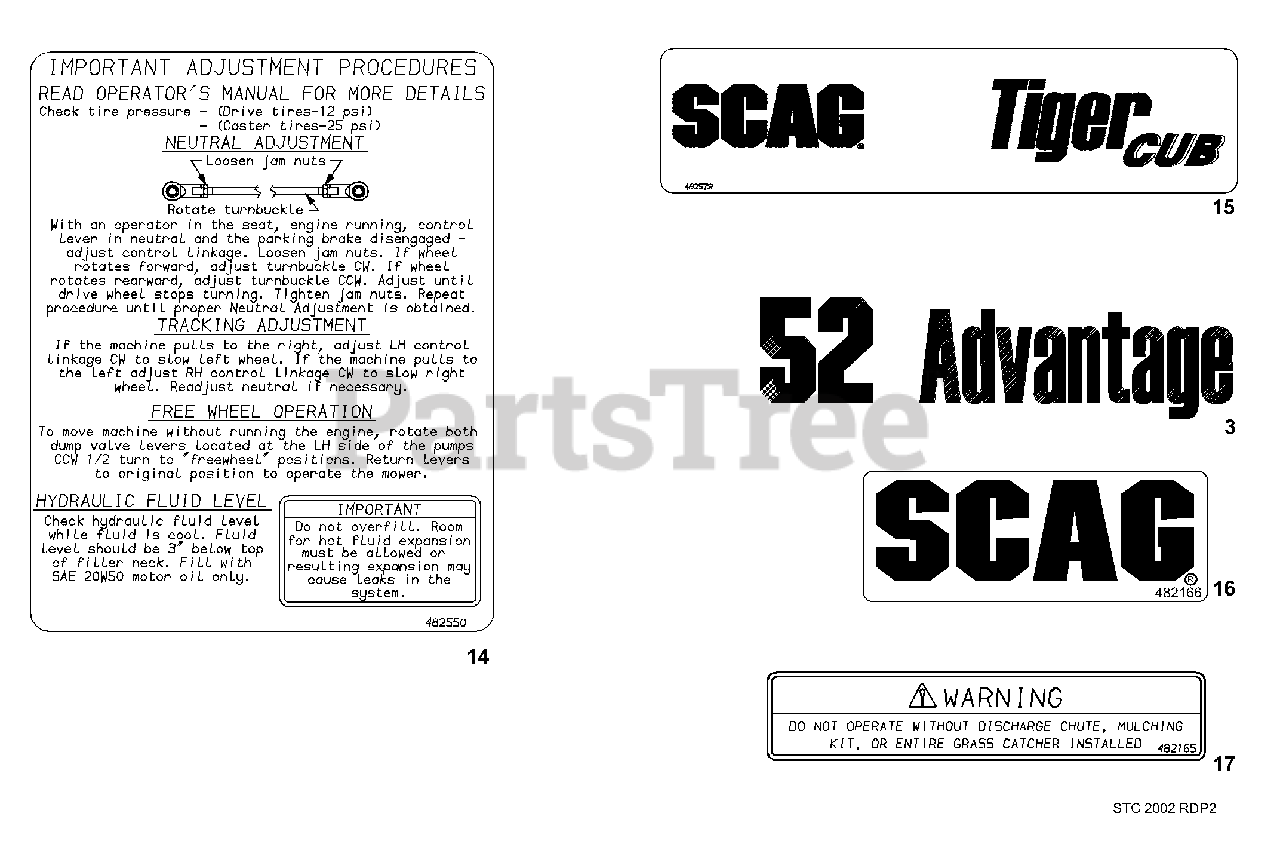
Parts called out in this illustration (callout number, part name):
3	Decal, 48A
14	Decal, Seat Support
15	Decal, Rear Bumper
16	Decal, Front Footplate
17	Decal, Discharge Chute
